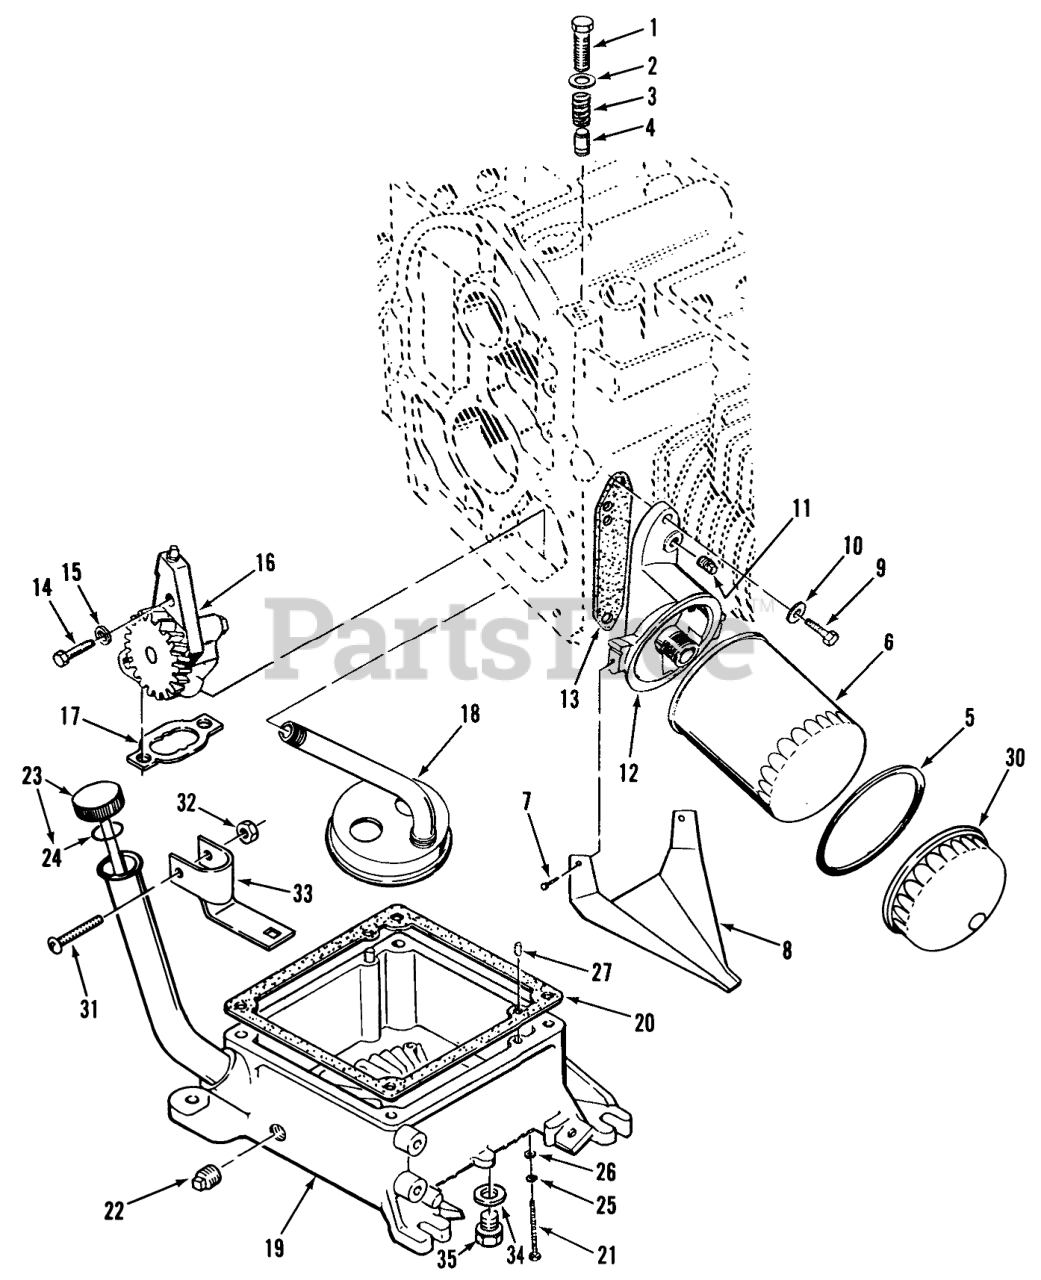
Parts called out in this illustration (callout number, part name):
1	Bolt
2	Washer
3	Spring
4	Piunger
5	Oil Fiter Seal
6	OIL FILTER
7	Bolt
8	OIL DRAIN
9	HHCS 5/16-18 X 1
10	Washer
11	Plug
12	Adapter
13	Gasket
14	Bolt
15	Washer-Lock
16	Oil Pump
17	Oil Pump Gasket Kit
18	Oil Pump Intake Cup
19	Oil Base (Includes all plugs and plug gasket)
20	Gasket
21	Screw 3/8-16 x 5-1/2
22	Plug
23	Oil Fill Cap and indicator
24	O-Ring
25	Washer 3/8
26	FLAT WASHER
27	Dowel Pin
30	Oil Filter Wrench
31	Screw
32	Nut
33	FILL TUBE BRACKET
34	Gasket
35	Plug
